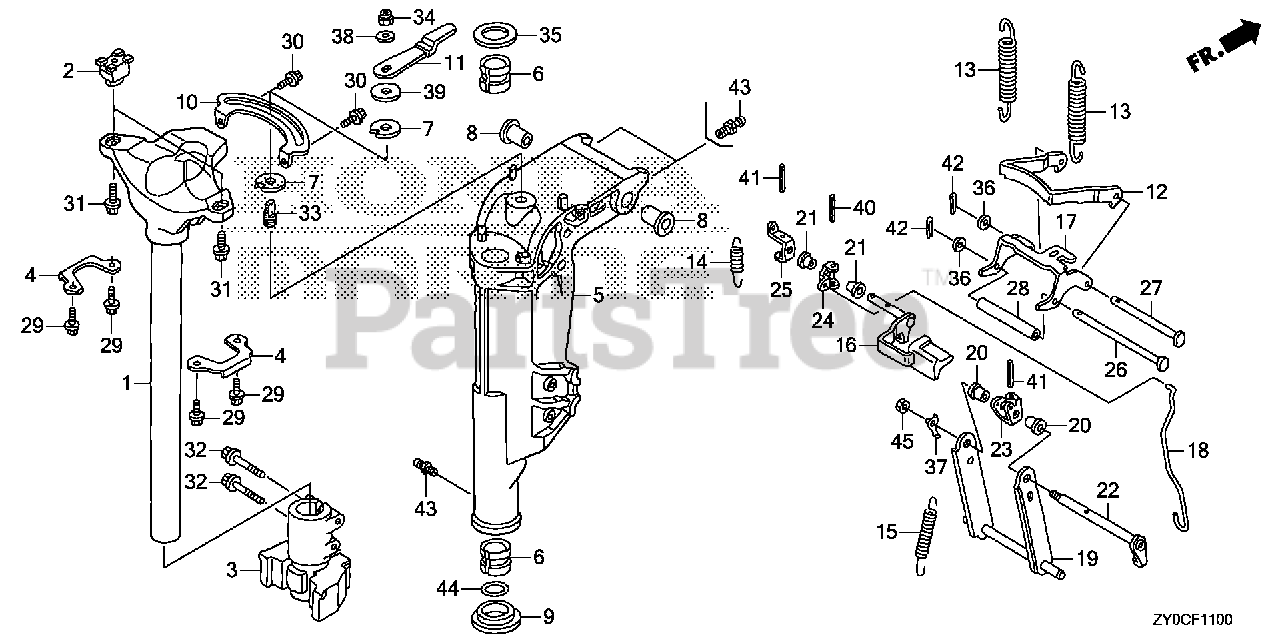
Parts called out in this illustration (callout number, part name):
1	FRAME, MOUNTING (L)
2	RUBBER, MOUNTING (UPPER)
3	RUBBER, MOUNTING (LOWER)
4	COVER, MOUNTING RUBBER (UPPER)
5	CASE, SWIVEL *NHB14M* (L) (AQUA MARINE SILVER METALLIC)
6	LINER, SWIVEL CASE
7	BLOCK, FRICTION
8	BUSH, SWIVEL CASE
9	COLLAR, SWIVEL CASE
10	PLATE, FRICTION
11	LEVER, FRICTION
12	HOOK, REVERSE LOCK
13	SPRING, REVERSE LOCK
14	SPRING, TILT LEVER
15	SPRING, TILT LINK
16	LEVER, TILT
17	ARM, REVERSE LOCK
18	ROD, RELEASE SWIVEL CASE
19	ARM, TILT
20	BUSH, TILT LEVER
21	BUSH, TILT LEVER
22	SHAFT, TILT
23	BRACKET, TILT SHAFT
24	BRACKET, RELEASE ROD
25	BRACKET, TILT LEVER
26	SHAFT, REVERSE LOCK (A)
27	SHAFT, REVERSE LOCK (B)
28	COLLAR, REVERSE LOCK
29	BOLT, FLANGE (6X12) Use from Frame SN 1005249.
30	BOLT, FLANGE (6X12)
31	BOLT, FLANGE (10X25)
32	BOLT, FLANGE (8X45)
33	BOLT, STUD (8X26)
34	NUT, SELF-LOCK (8MM)
35	WASHER, THRUST
36	WASHER, PLAIN (6MM) Use from Frame SN 4800713.
37	WASHER, LOCK
38	WASHER (8MM)
39	WASHER, NYLON (8MM)
40	PIN, SPRING (3.0X22)
41	PIN, SPRING (3.0X25)
42	PIN, SPLIT (2.0)
43	NIPPLE, GREASE
44	O-RING (34X2.4)
45	NUT, HEX. (6MM)
